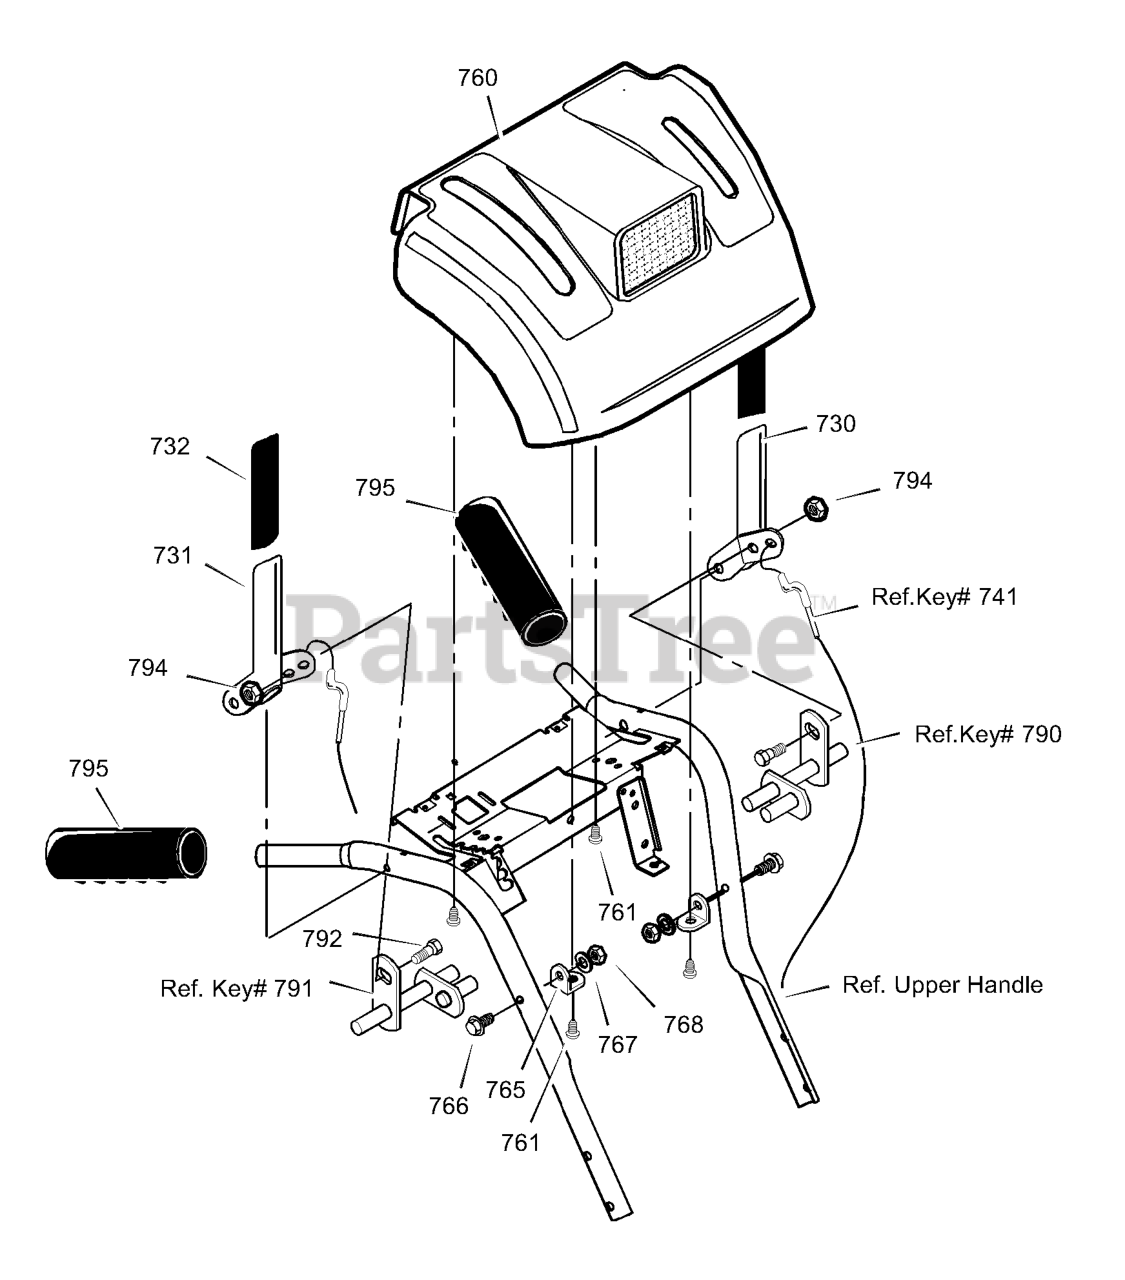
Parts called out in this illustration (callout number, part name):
730	CLUTCH HANDLE LH
731	CLUTCH HANDLE RH
732	GRIP, CLUTCH LEVER
760	PANEL, CONTROL
761	SCREW, 10 X .62
765	BRACKET, PANEL
766	SCREW, 5/16-18 x 1.75
767	WASHER, HVSPTLK
768	NUT, 5/16-18
792	BOLT, 1/4-20 X .50
794	NUT, 1/4-20
